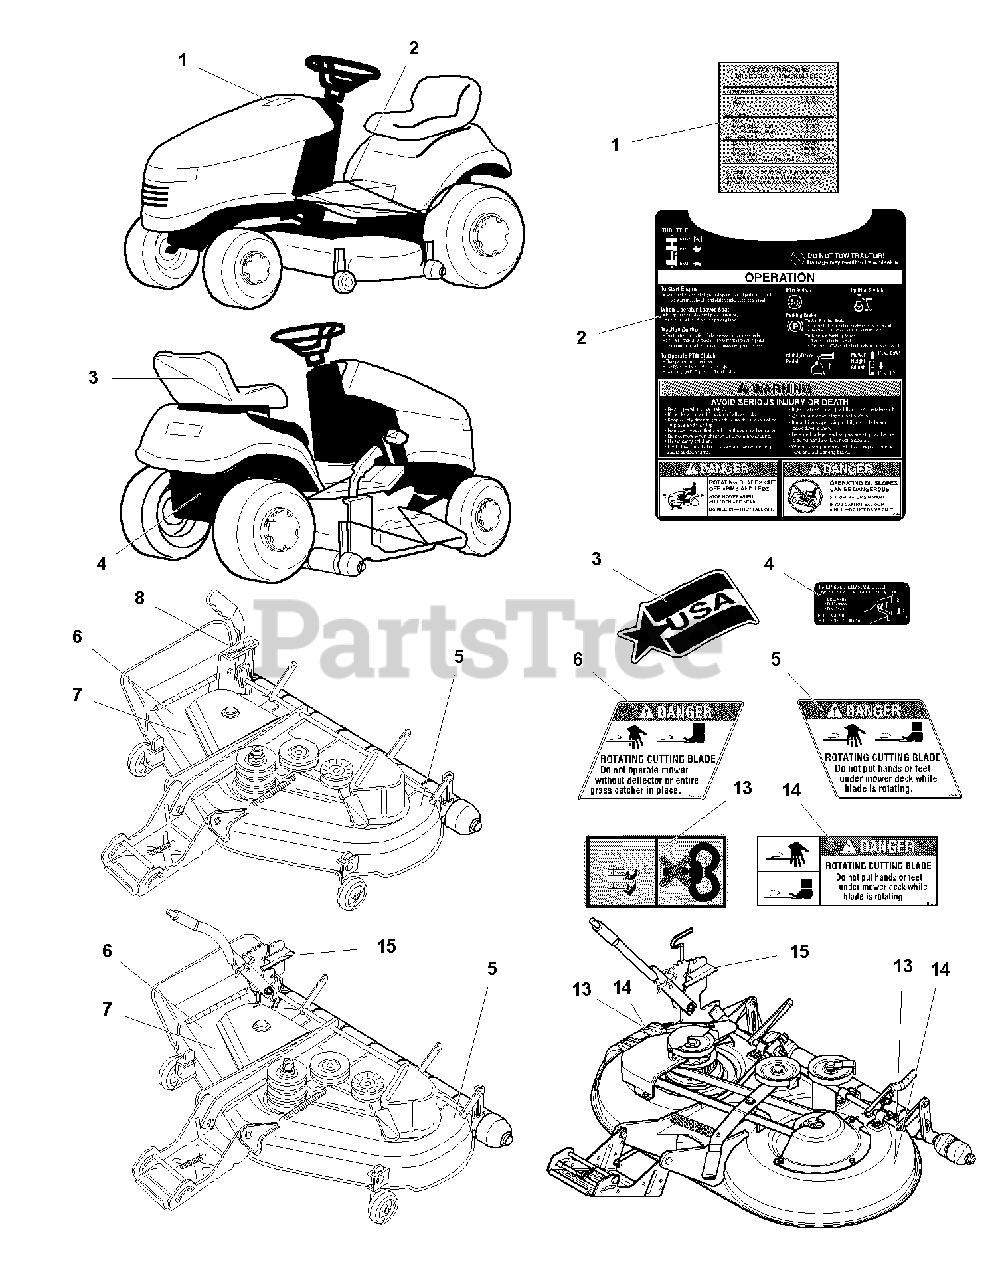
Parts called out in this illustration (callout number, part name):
1	DECAL, Belt/Blade
2	DECAL, Operating Instructions
3	DECAL, Logo, USA
4	DECAL, Release Valve
5	DECAL, Danger, Rotating Cutting Blade
5	DECAL, Danger, Rotating Cutting Blade, 40"
6	DECAL, Danger, Chute in Place
7	DECAL, Cutting Width, 38"
7	DECAL, Cutting Width, 44"
8	DECAL, Height of Cut
9	DECAL, OPEI (Not Serviced)
10	PLATE, Manufacturing No./Serial No. (Not Serviced)
11	DECAL, Decibel (Export only)
12	DECAL, CE (Export only)
13	DECAL, Danger, Rotating Cutting Blade, 40" (Export only)
14	DECAL, Danger, Rotating Cutting Blade, 40"
15	DECAL, Height of Cut, 38" & 44" Curved Handle, 40" Mulcher
